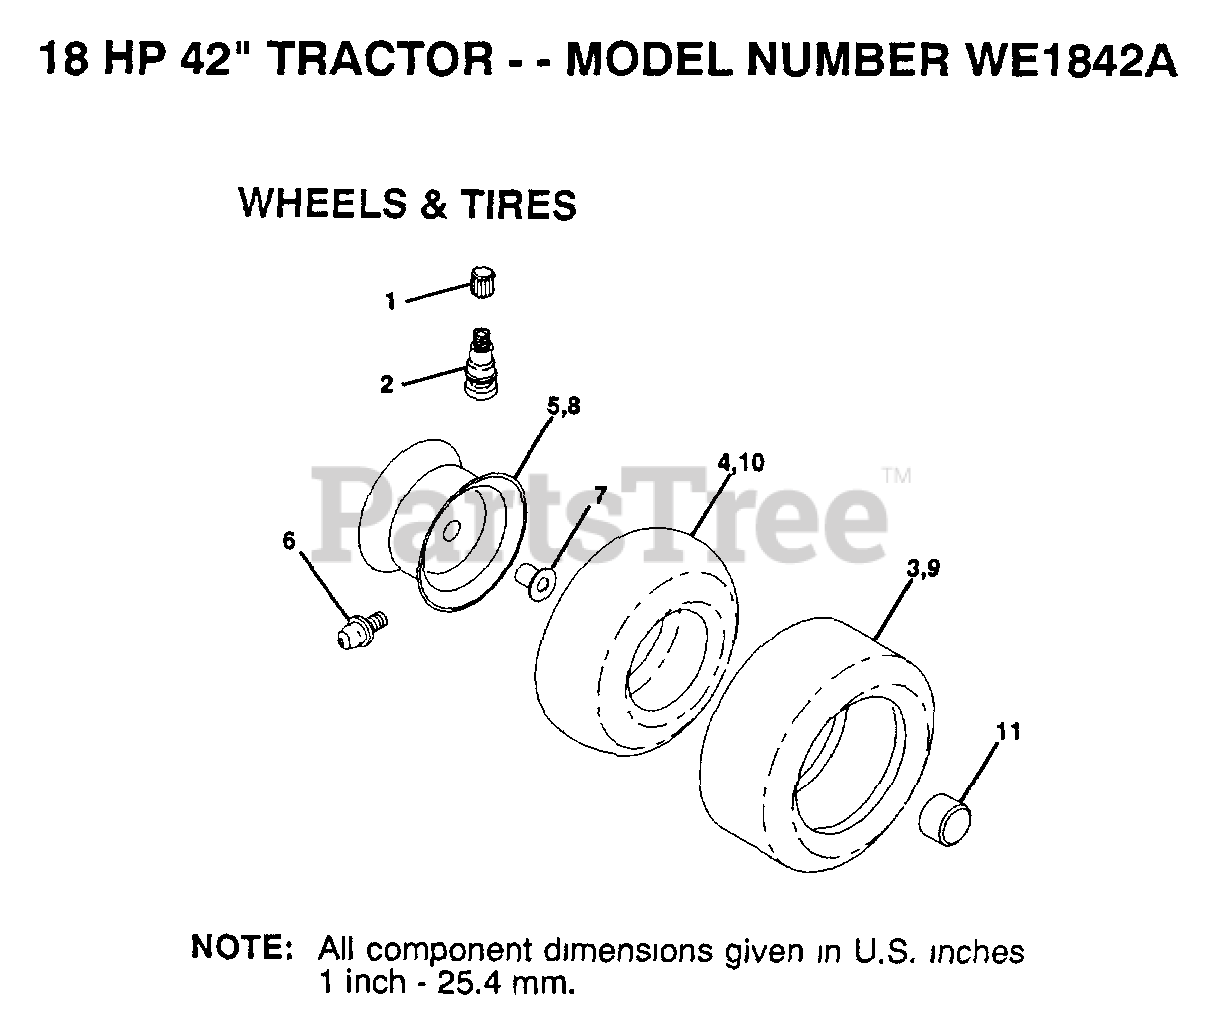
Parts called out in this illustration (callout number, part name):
1	VALVE CAP
2	VALVE STEM LT
4	TUBE.5.3/4.5/6
5	"RIM.ASM.6""FRONT"
6	FITTING LT
7	"FLANGE, BEARING"
8	"RIM.ASM.8""REAR"
10	TUBE.18X9.5-8
11	HUB CAP
